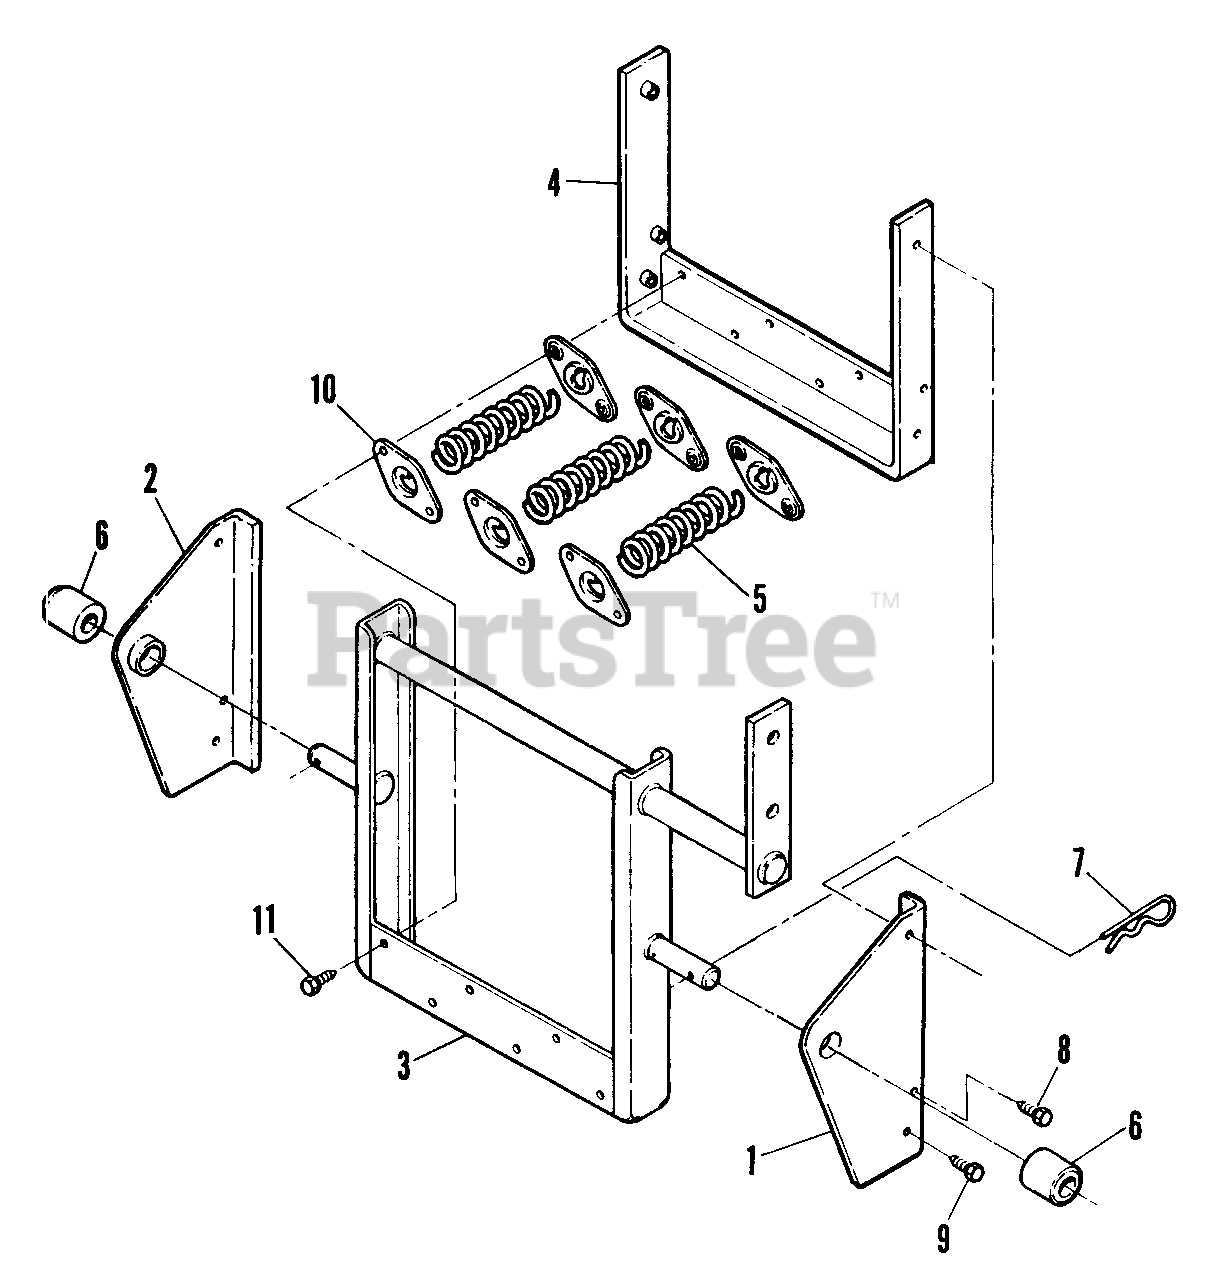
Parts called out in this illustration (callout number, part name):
1	BRACKET, Right Half Mounting
2	BRACKET, Left Half Mounting
3	STRUCTURE, Lift Yoke
4	STRUCTURE, Spring Strap
6	BUSHING, Hitch
7	PIN, Cotter - Hair
8	SCREW, 5/16 - 18 x 1 Hex Thread Forming
9	SCREW, 5/16 - 18 x 3/4 Hex Thread Forming
10	RETAINER SPRING
11	SCREW, 3/4 - 20 x 1/2 Self Tap
